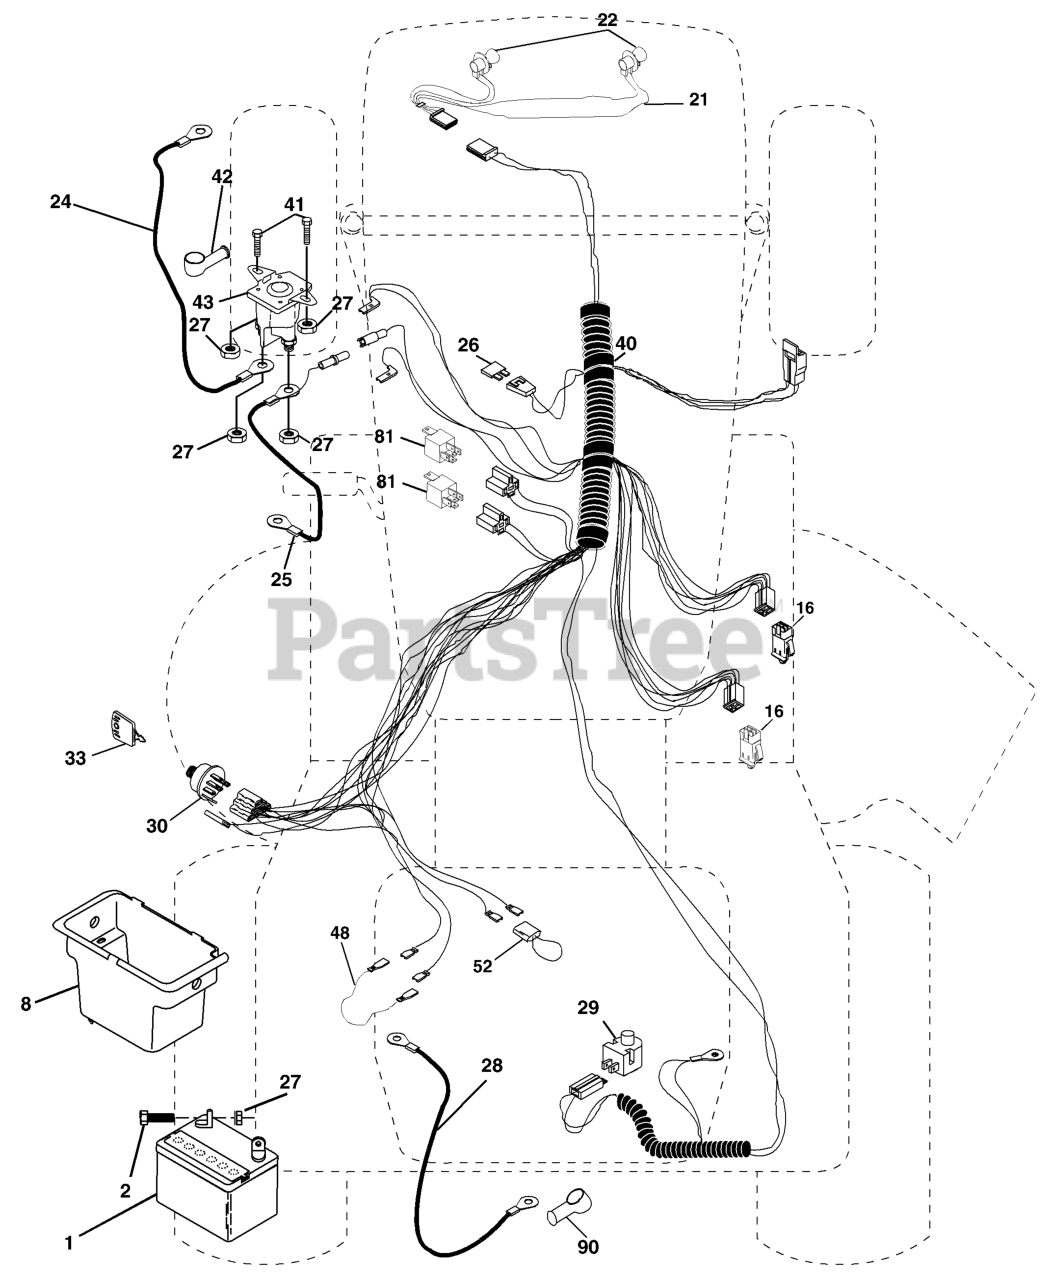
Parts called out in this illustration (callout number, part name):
1	Battery 12 Volt 28 AMP
2	BOLT.HEX.1/4.X.3/4.DICHROMATE
8	BOX.BATTERY.FENDER
16	INTERLOCK SWITCH
21	HARNESS.W/LIGHT SOCKET
24	BATTERY CABLE GT
25	CABLE BATTERY
26	FUSE 20AMP
27	NUT
28	CABLE T
29	PLUNGER SWITCH (COLOR:OLIVE)
30	IGNITION SWITCH
33	KEY MLD GEN DELTA
40	HARNESS IGN.
41	BOLT
42	TERMINAL COVER
43	SOLENOID
48	ADAPTER.AMMETER
52	WIRE PROTECTION LOOP
81	RELAY.ASSY.T
90	COVER TERMINAL
